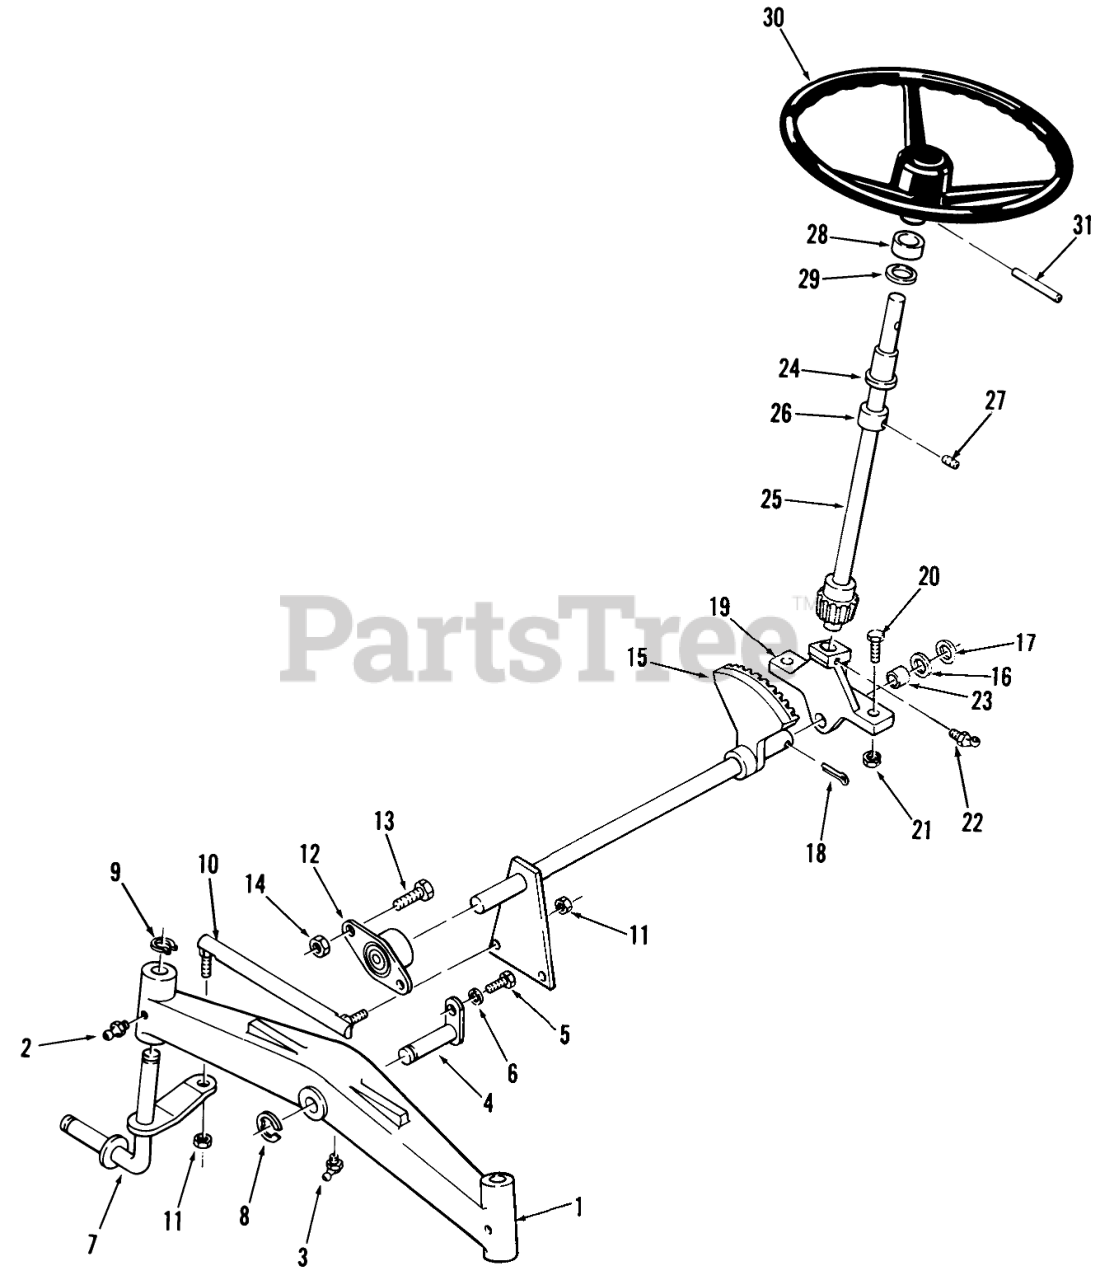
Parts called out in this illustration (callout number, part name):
1	AXLE-FRONT
2	Zerk
3	FITTING-GREASE
4	PIN AND PLATE ASM
5	H H C S
6	Lockwasher
7	Front Spindle RH
7	Front Spindle LH
8	E-RING
9	Snap Ring
10	Tie Rod RH
10	Tie Rod LH
11	NUT-6
12	BEARING-FLANGED
13	Bolt
14	Nut
15	Assy-Steering
16	WASHER-SHIM
17	WASHER
18	PIN-4
19	Support
20	Bolt
21	Nut
22	FITTING-GREASE
23	BEARING-BRONZE
24	BEARING
25	Shaft-Upper Steering
26	Collar
27	SCREW-SET
28	COLLAR
29	WASHER-BOWED
30	STEERING WH 13" PLAS
31	Pin-Roll
